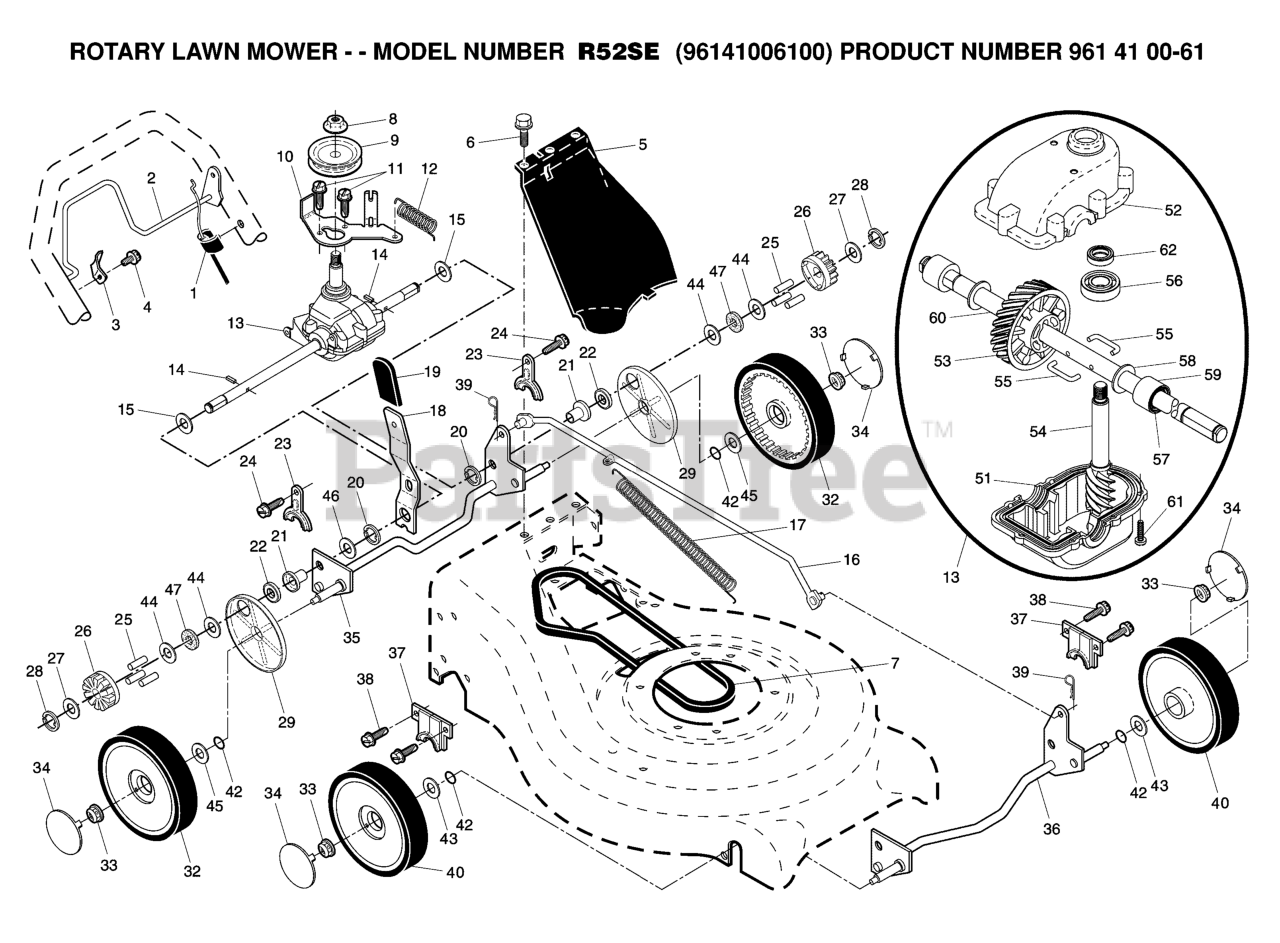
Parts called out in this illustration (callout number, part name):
1	DRIVE CABLE
3	DOWNSTOP BRACKET
5	COVER.DRIVE.21.RWGD.MO
8	FLANGED LOCKNUT 3/8-16 ZINC
10	BELT GUIDE
13	TRANSMISSION.21.RWGD.FRANCE
14	PIN.SPRING.THRUST
15	THRUST WASHER
16	ROD CONNECTING
17	SPRING
18	SPRING.SELECTOR.SPT.21
19	KNOB.EXT.ERGO.BLACK
21	RP BEARING SUPPORT
22	BEARING, BALL
23	BRACKET
25	PAWL.DRIVE.ETCHED
26	PINION.DRIVE.WALK
28	E-RING 7/16 RE
29	COVER.DUST.WHEEL
32	WHEEL.9X2.PR.LP.RADIAL.BK.BB.3
33	WHEEL 9X2
34	HUBCAP
35	SHAFT.ASM.REAR.TORQUE
36	SHAFT ASSY FRONT
37	RETAINER.FRONT.SHAFT
39	RETAINER CLIP
40	FRONT.WHEEL.8X2
42	O-RING
43	WASHER.FLAT.1/2
44	WASHER.BELLEVILLE (3 2 LB)
45	WASHER FLUT
46	WASHER.ZINC.PLATED
51	CASE, LOWER
52	GEARCASE.HOUSING
53	GEAR.24.TOOTH.WALK.MOWER
54	SHAFT INPUT
55	WIRE, FORMED (15966)
57	SEAL.OUTPUT.SHAFT
62	SEAL INPUT SHAFT
